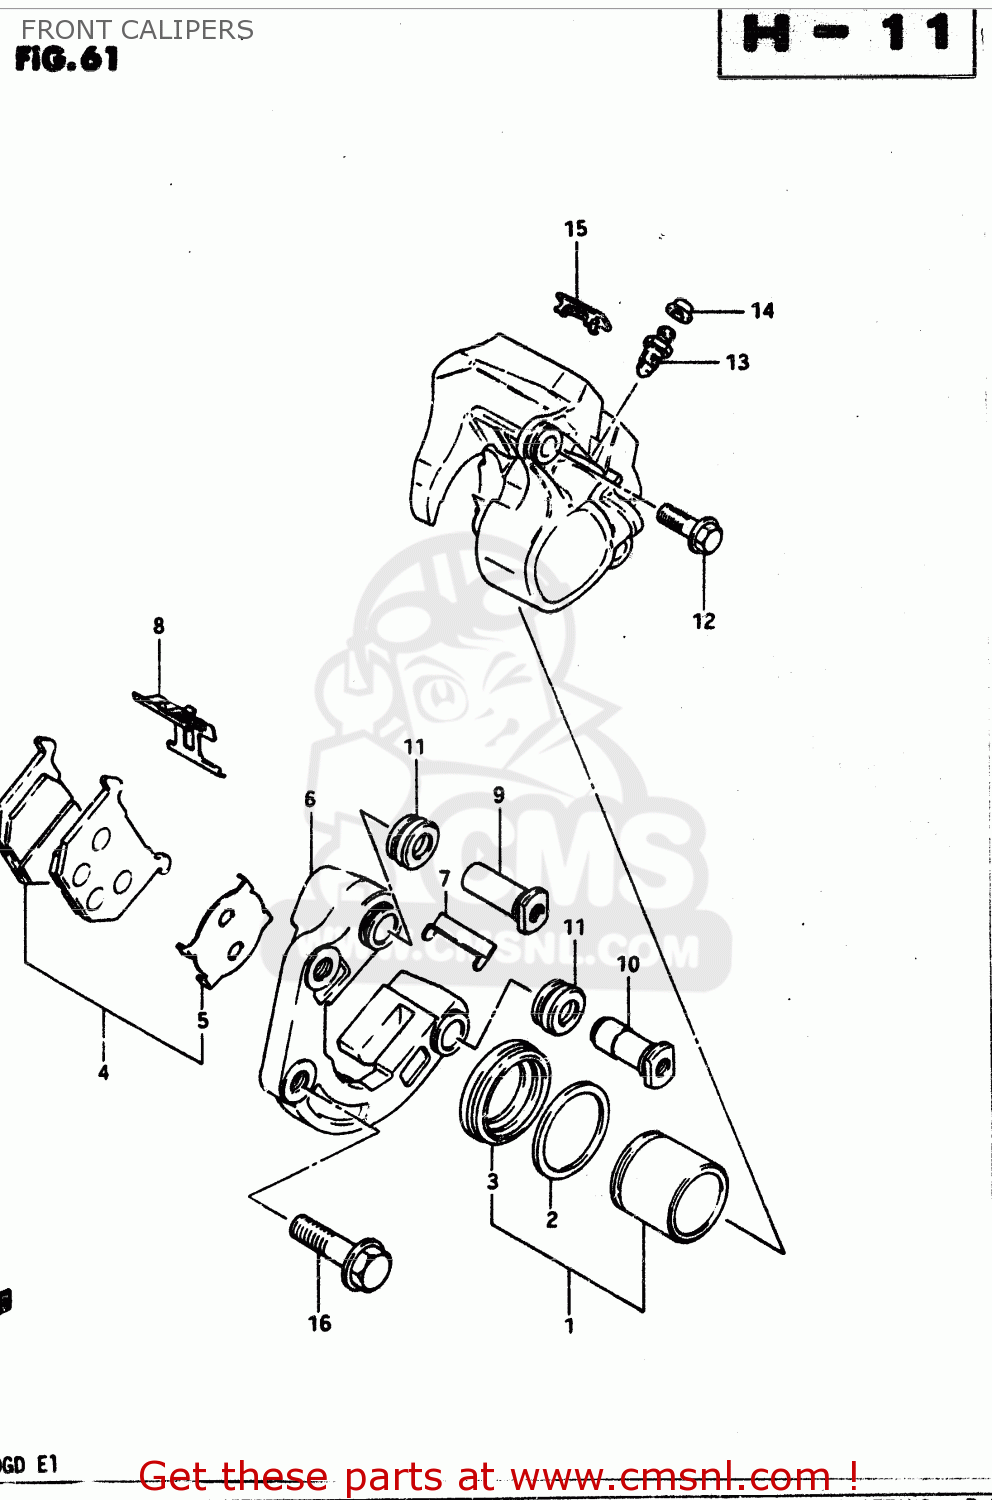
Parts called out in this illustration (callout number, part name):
1	PISTON SET
2	SEAL,PISTON
3	BOOT,PISTON
4	PAD SET (MCA)
5	SHIM,PAD
6	CARRIER,CALIPER,LEFT
7	GUIDE,PAD
8	SPRING,PAD
9	AXLE NO.1
10	AXLE NO.2
11	BOOT,AXLE
12	BOLT
13	BLEEDER
14	CAP,BREATHER
15	COVER
16	BOLT(10X37)
